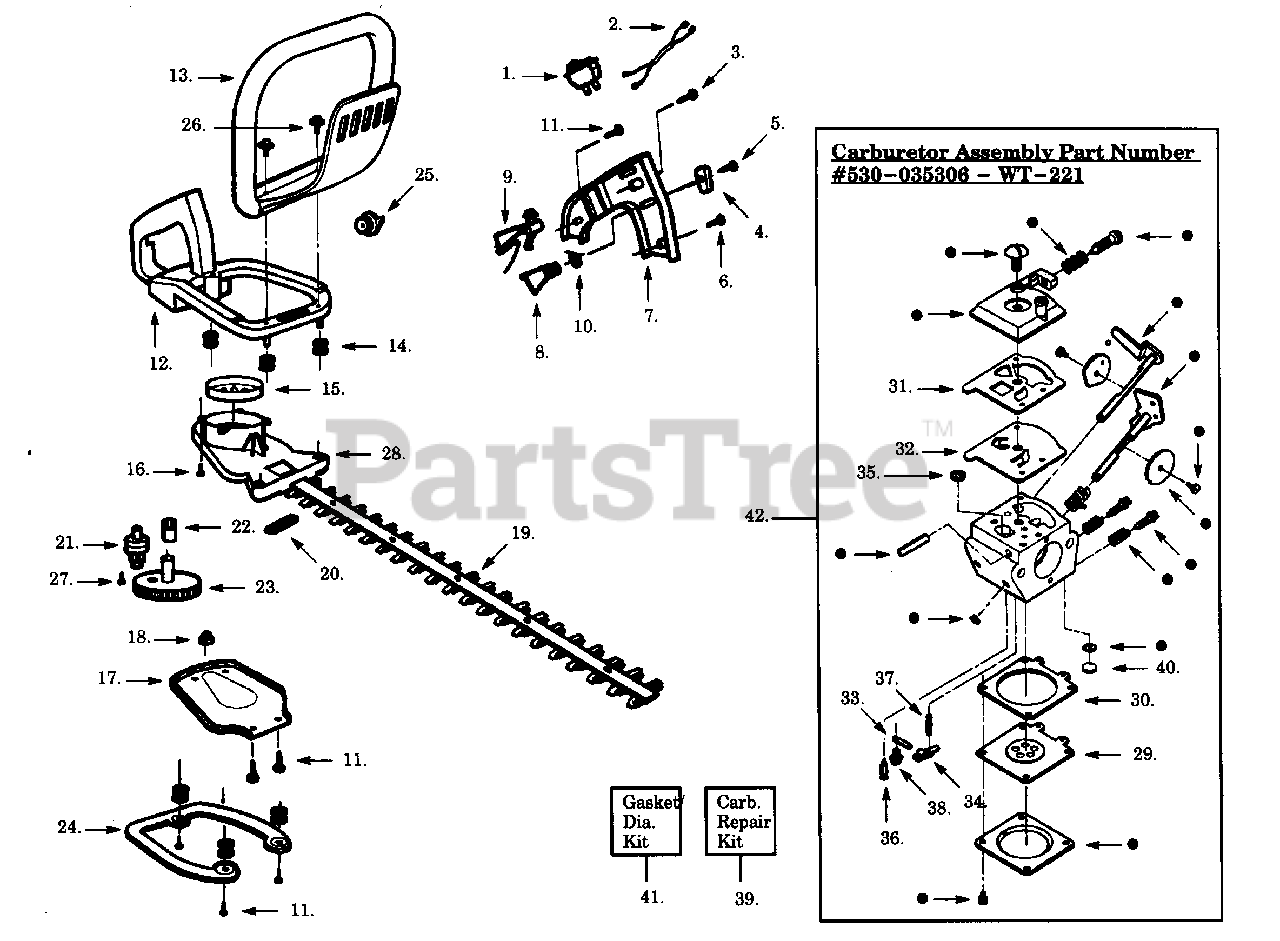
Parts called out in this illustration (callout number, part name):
1	Ignition Switch
2	Lead Wire Ass'y.
4	Trigger Lever
7	Handle Cover
8	Throttle Trigger
9	Throttle Lockout
10	Trigger Spring
12	Rear Handle & Tank Ass'y.
13	Front Handle
14	Isolator Spring
15	Clutch Drum
17	Gear Box Plate
18	Bushing Blade
19	Blade Ass'y. (22")
20	Blade Seal
21	Pinion Ass'y.
22	Drive Gear Bearings
23	Drive Gear Ass'y.
24	Isolator Plate
25	Fuel Cap Ass'y.
27	Screw
28	Gear Box Ass'y. (Inc. 21, 22 & 27)
29	Metering Diaphragm
30	Metering Diaphragm Gasket
31	Pump Gasket
32	Pump Diaphragm
33	Metering Pin
34	Metering Lever
35	Fuel Inlet Screen
36	Inlet Needle Valve
37	Metering Lever Spring
38	Metering Lever Pin Screw
39	Carburetor Repair Kit (Inc. 33,34,35,36,37, 38,40)
40	Welch Plug
41	Gasket/Diaphragm Kit (Inc. 29,30,31,32)
42	Carburetor Ass'y. WT-221
